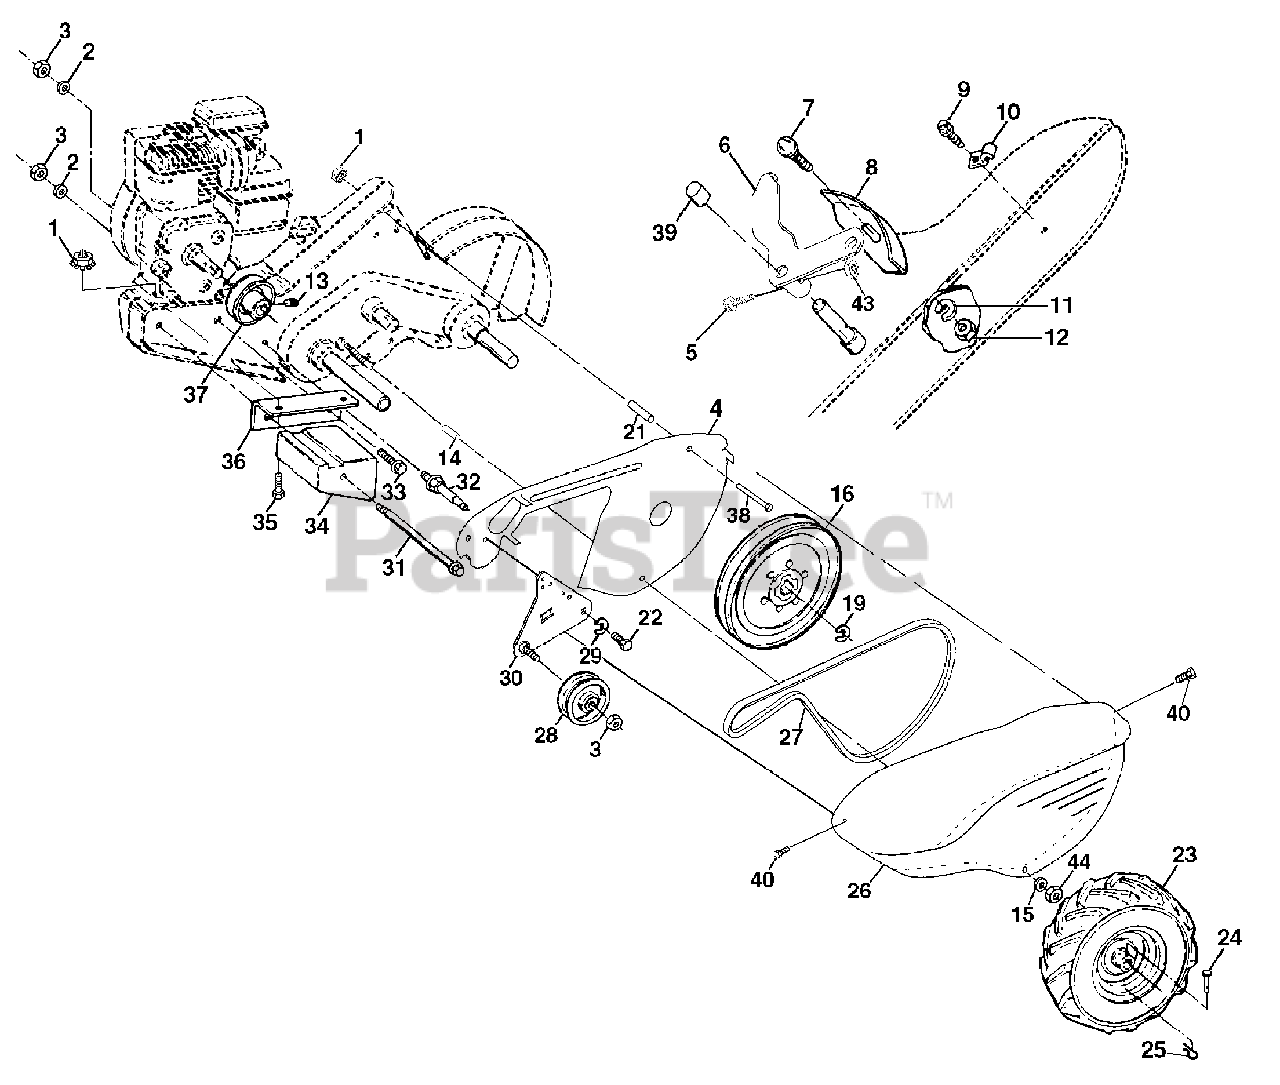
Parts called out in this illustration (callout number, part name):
1	Nut, Keps 5/16-18
2	Washer, Lock 3/8
3	Nut, Hex 3/8-16
4	Shield, Inner Belt Guard
5	Screw, Shift Lever
6	Lever, Shift
7	Bolt, Carriage 1/4-20 x 1/2 Gr. 5
8	Plate, Shift Indicator
9	Screw, Hex, Washer Head, Slotted #10-24 x 1/2
10	Clip
11	Washer, Lock 1/4
12	Nut, Hex 1/4-20
13	Screw, Set, Hex 5/16-18 x 3/8
14	Spacer, Split 0.327 x 0.42 x 1.220
15	Washer 11/32 x 11/16 x 16 Ga.
16	Sheave, Transmission
19	Ring, Retainer
21	Spacer, Split 0.327 x 0.42 x 2.09
22	Bolt, Fin Hex 5/16-24 x 1/2
23	Tire
23	Tire Valve
24	Rivet, Drilled
25	Clip, Hairpin
26	Guard, Belt
27	Belt, V
28	Pulley, Idler
29	Ring, Klip
30	Bracket, Idler
31	Bolt, Hex 5/16-16 x 12
32	Shaft, Idler Arm
33	Bolt, Hex 3/8-16 x 1
34	Counterweight, L. H.
35	Bolt, Hex 5/16-18 x 1-1/2
36	Bracket, Reinforcement, L. H.
37	Sheave, Engine
38	Bolt, Fin Hex 5/16-18 x 2-3/4
39	Cap, Plunger
40	Screw Hex Wsh Slt #10-24 x .50
43	Nut, Lock #10-24
44	Nut, Lock 5/16-18
